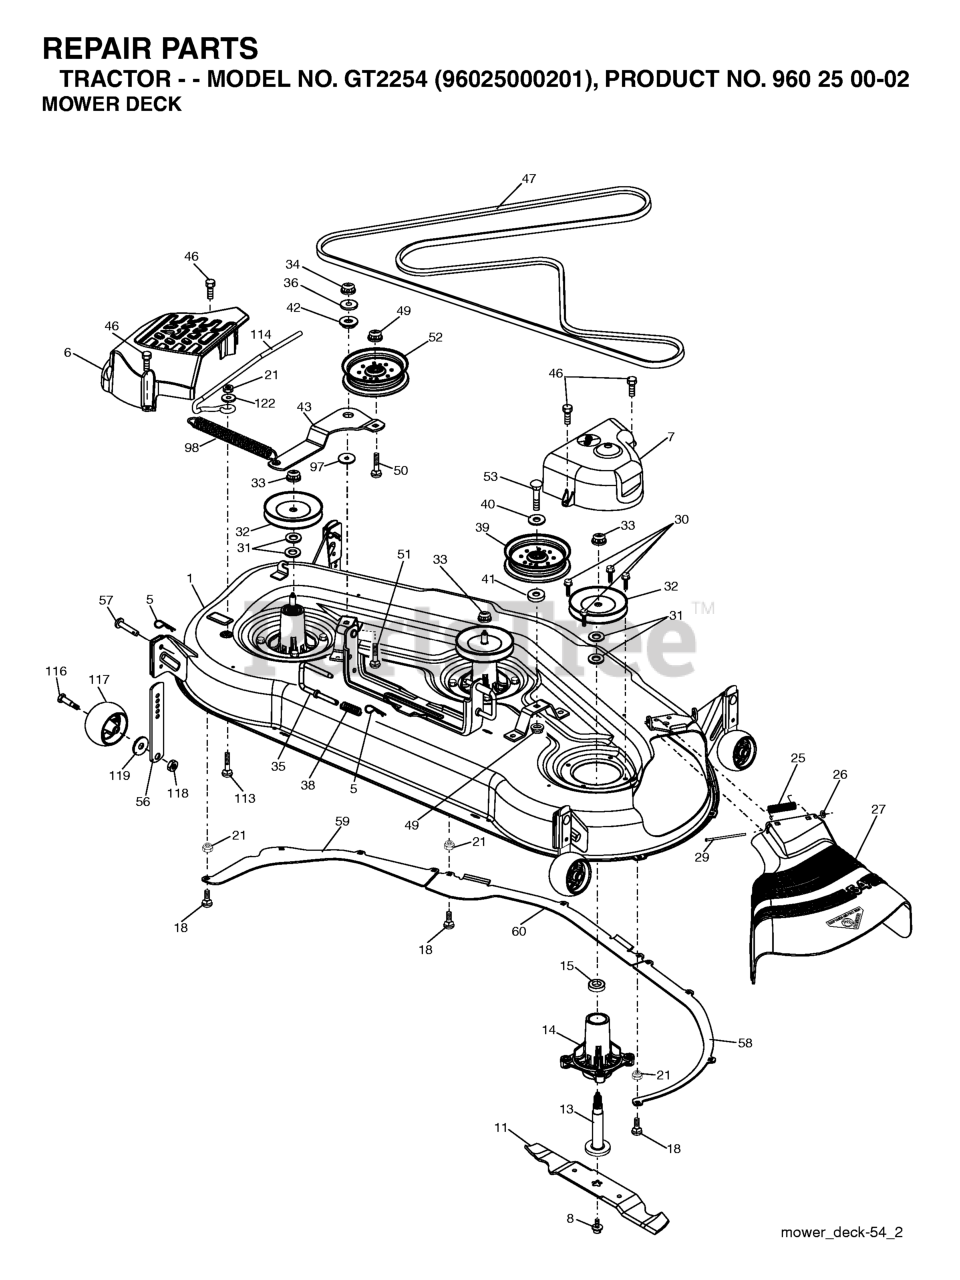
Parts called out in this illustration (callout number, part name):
1	DECK.PNT.WLDMENT.54"
5	RETAINER-SPRNG RB
6	COVER.MANDREL.LH.DECK.54"
7	COVER.MANDREL.RH.DECK.54"
8	BOLT 7/16 ASM BLADE
11	48" Hi-lift Blade
13	SHAFT ASM MANDREL
14	RP.HOUSING.MANDREL.4PT.
18	BOLT
21	LOCKNUT
25	SPRING, TORSION
26	NUT PUSH M
27	DEFLECTOR
29	ROD.HINGE
30	SCREW, WASHER HEAD
31	WASHER.SPACER.MANDREL
32	PULLEY MANDREL
33	NUT, FLG TOPLOCK 9/16"
35	PIN.SUSPENSION.REAR.54"
36	WASHER
38	SPRING COMPRESSION PULL
39	PULLEY.IDLER.STATIONARY
40	Washer 13/32 x 1-3/8 x 13 Ga.
41	WASHER
42	SPACER RETAINER
43	ARM.IDLER.54"
46	SCREW.1/4-20X5/8
47	V-BELT 54" HIGH PERFORMANCE
49	NUT LOCK FLG 3/8-16 UNC
51	BOLT
52	IDLER PULLEY
53	BOLT.HEX
56	BAR.ADJUST.WHEEL.ANTI.SCALP.BL
57	RIVET.PIN.HEAD.YELLOW.
58	BAFFLE.RIGHT.54"
59	BAFFLE.LEFT.54"
60	BAFFLE CENTER 54" MOWER
97	WASHER 12/32X2X10GA
98	SPRING.CLUTCH.DRIVE.54
114	ROD TENSION RELIEF
116	BOLT.SHOULDER.3/8-16X3-5/8.
117	RP WHEEL. GUAGE RALLY
118	LOCKNUT
119	WASHER.5/16.FLAT.STE.STD.
122	BUSHING.RELIEF.TENSION
